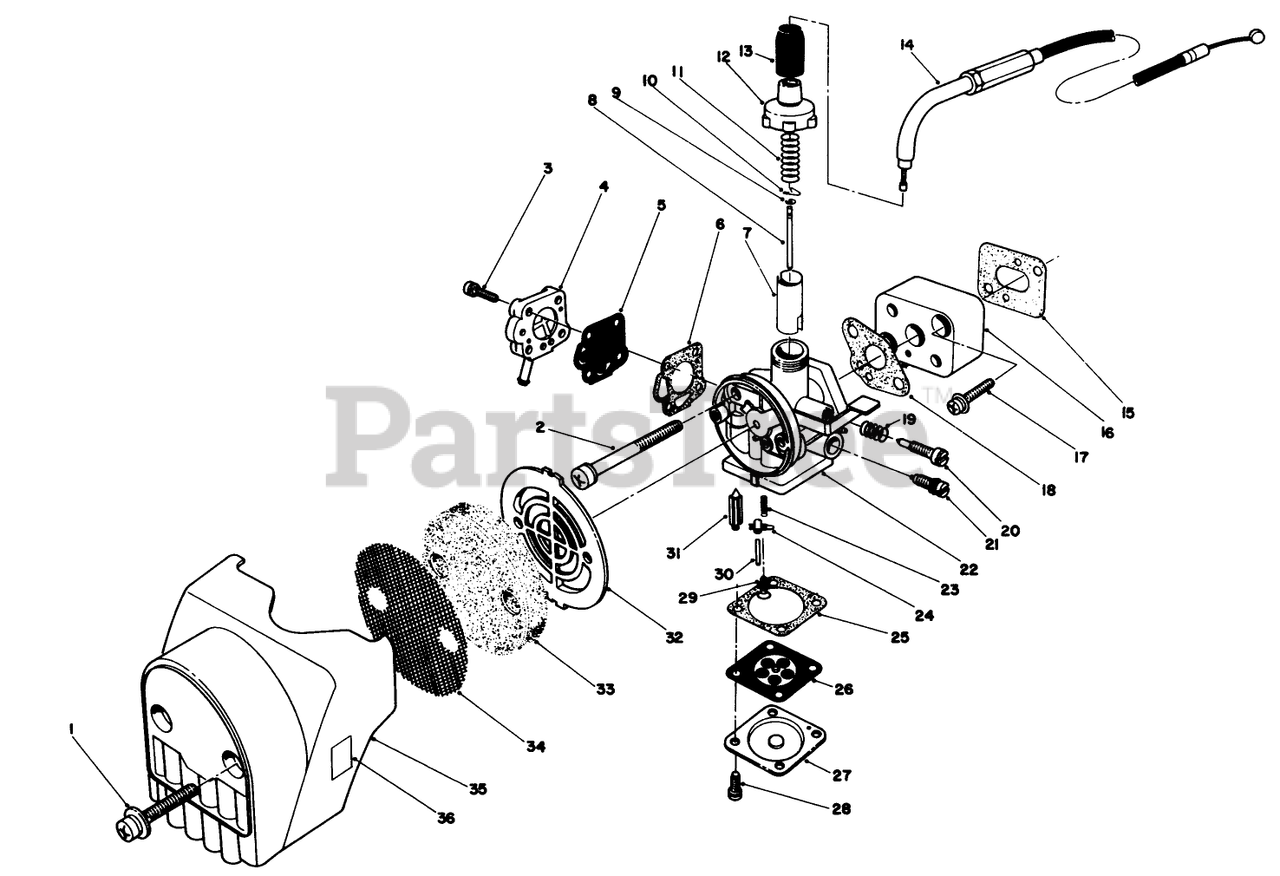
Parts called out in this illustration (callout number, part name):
2	SCREW W/ WASHER
13	AIR SEAL
15	GASKET, INSULATOR
21	MAIN NEEDLE
22	CARBURETOR (D)
24	FLOAT ARM
25	DIAPHRAGM GASKET
27	DIAPHRAGM COVER
29	FLOAT SCREW
33	ELEMENT
35	COVER, CLEANER
36	CHOKE LABEL
